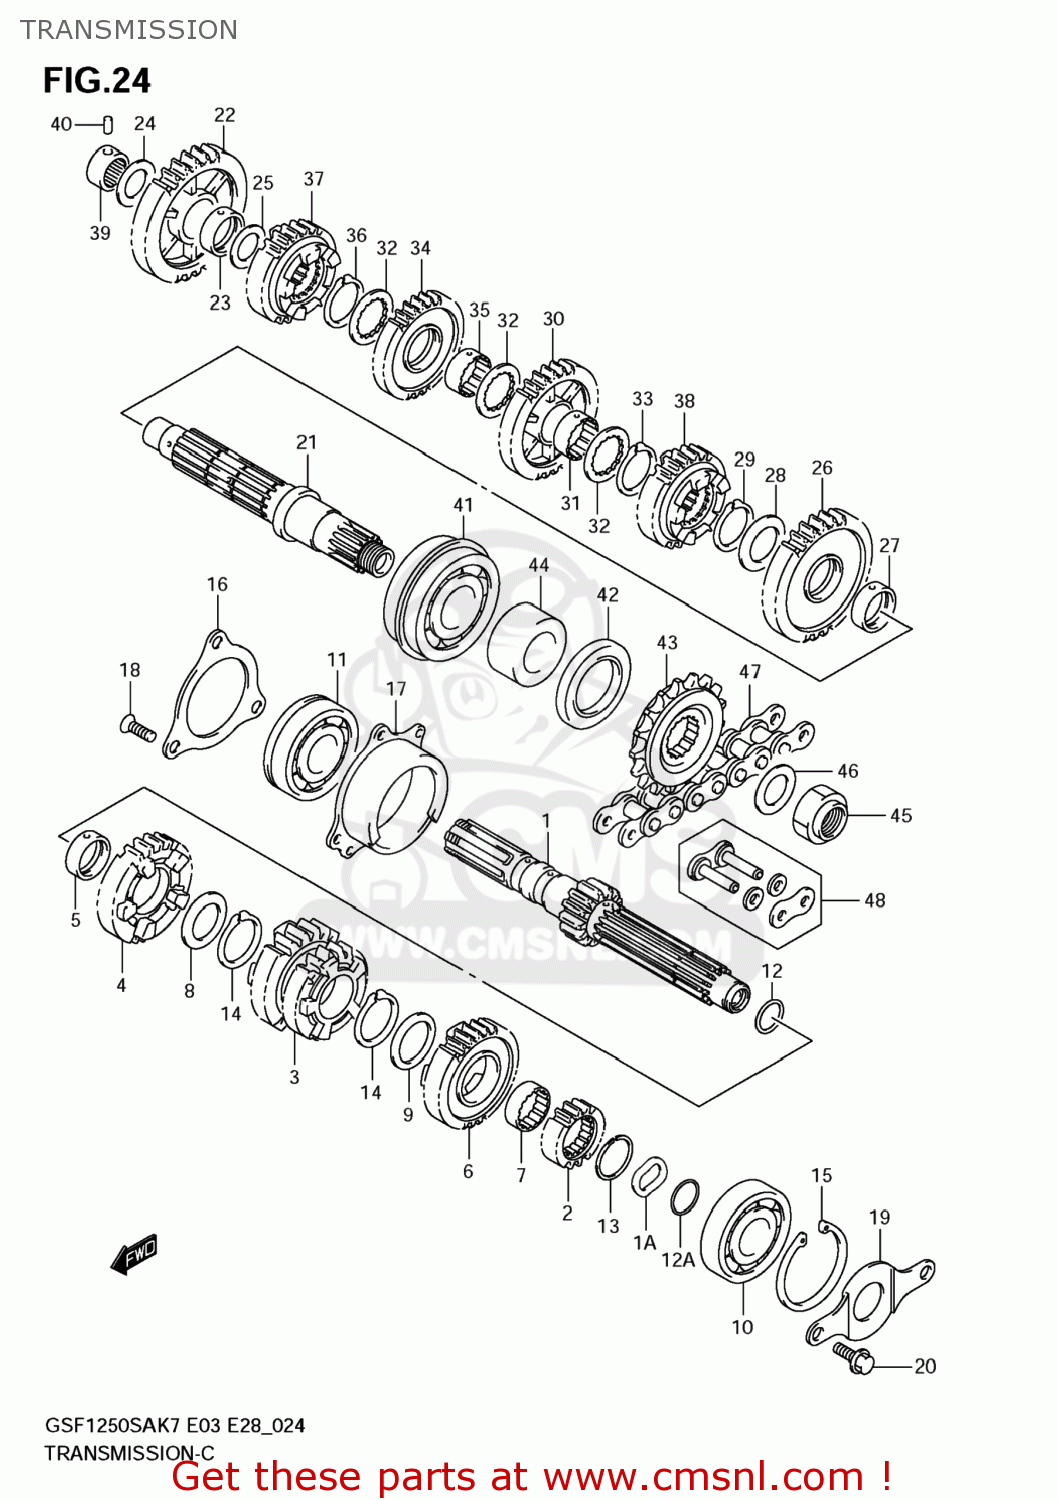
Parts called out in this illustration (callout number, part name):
1	SHAFT,COUNTER(NT:13)
1A	WASHER,COUNTER SHAFT WAVE
2	GEAR,2ND DRIVE
3	GEAR,3RD & 4TH DRIVE(NT:20/23)
4	GEAR,5TH DRIVE(NT:25)
5	BUSH,5TH DRIVE GEAR
6	GEAR,6TH DRIVE(NT:28)
7	BUSH,6TH DRIVE GEAR
8	WASHER(27X36X1)
9	WASHER,LOCK
10	BEARING(20X52X15)
11	BEARING(25X62X17)
12	O RING(D:1.9,ID:16.6)
12A	O RING(D:1,ID:19.5)
13	CIRCLIP
14	CIRCLIP
15	CIRCLIP
16	RETAINER,CNTR SHAFT BEARING,R
17	HOUSING,CNTR SHAFT BRG,R
18	SCREW(6X20)
19	RETAINER,CL PUSH ROD OIL SEAL
20	BOLT(6X12)
21	SHAFT,DRIVE
22	GEAR,1ST DRIVEN(NT:40)
23	BUSH
24	SHIM(20X34X1)
25	SHIM(22X34X1)
26	GEAR,2ND DRIVEN(NT:35)
27	BUSH,2ND DRIVEN GEAR
28	WASHER(27X36X1)
29	CIRCLIP
30	GEAR,3RD DRIVEN(NT:31)
31	BUSH
32	WASHER,3RD & 4TH DRIVEN
33	CIRCLIP
34	GEAR,4TH DRIVEN(NT:30)
35	BUSH
36	CIRCLIP
37	GEAR,5TH DRIVEN(NT:29)
38	GEAR,6TH DRIVEN(NT:30)
39	BEARING(20X34X13.5)
40	PIN(6X10)
41	BEARING(30X62X23.8)
42	SEAL,OIL(42X62X7)
43	SPROCKET,ENGINE(NT:18)
44	SPACER,ENGINE SPROCKET
45	NUT
46	WASHER(25X40X1.4)
47	CHAIN,DRIVE(RK50GSVZ3M)
48	JOINT SET
